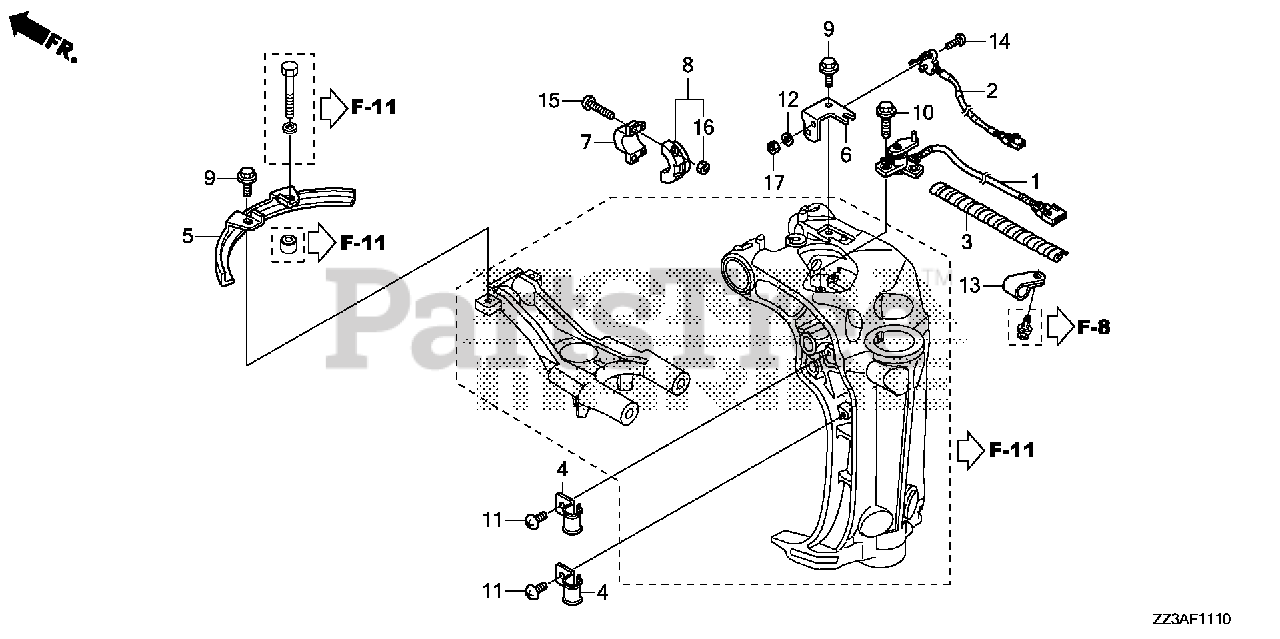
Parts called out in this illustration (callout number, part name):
1	SENSOR ASSY., RUDDER
2	SWITCH ASSY., TILT LIMIT
3	TUBE, SPIRAL
4	CLAMP, TUBE
5	PLATE, STEERING ANGLE SENSOR
6	BRACKET, TILT LIMIT SENSOR
7	CAM A, TILT LIMIT ANGLE
8	CAM B, TILT LIMIT ANGLE
9	BOLT, FLANGE (6X12)
10	BOLT, FLANGE (6X20)
11	SCREW, PAN (6X8)
12	WASHER, PLAIN (4MM)
13	CLIP (14MM)
14	SCREW, PAN (4X14)
15	SCREW, PAN (5X20)
16	NUT, HEX. (5MM)
17	NUT, HEX. (4MM)
